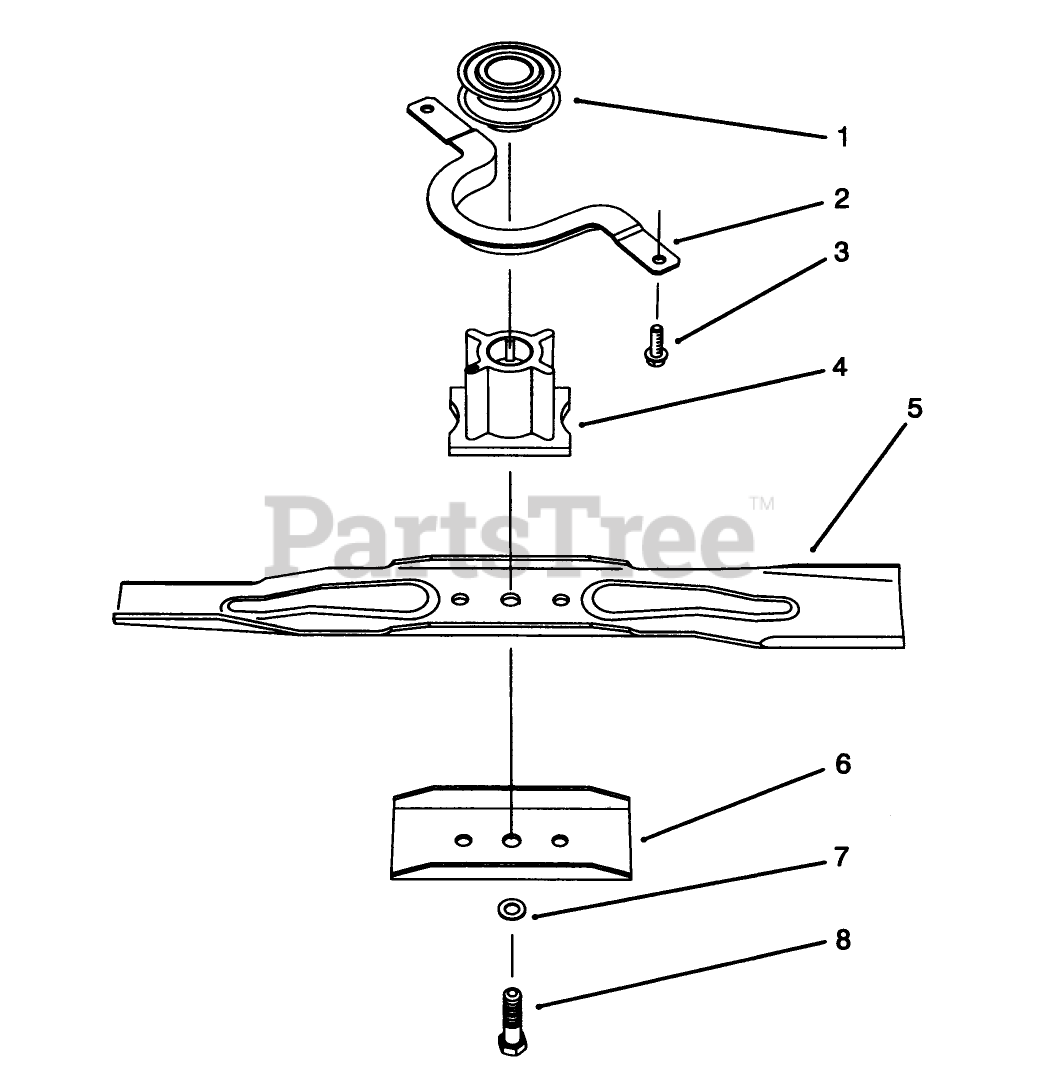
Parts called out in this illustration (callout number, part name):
1	PULLEY-DRIVE, ZONE START
3	SCREW-HWH
5	Blade
6	Stiffener Blade
7	WASHER-LOCK
8	BOLT-BLADE
